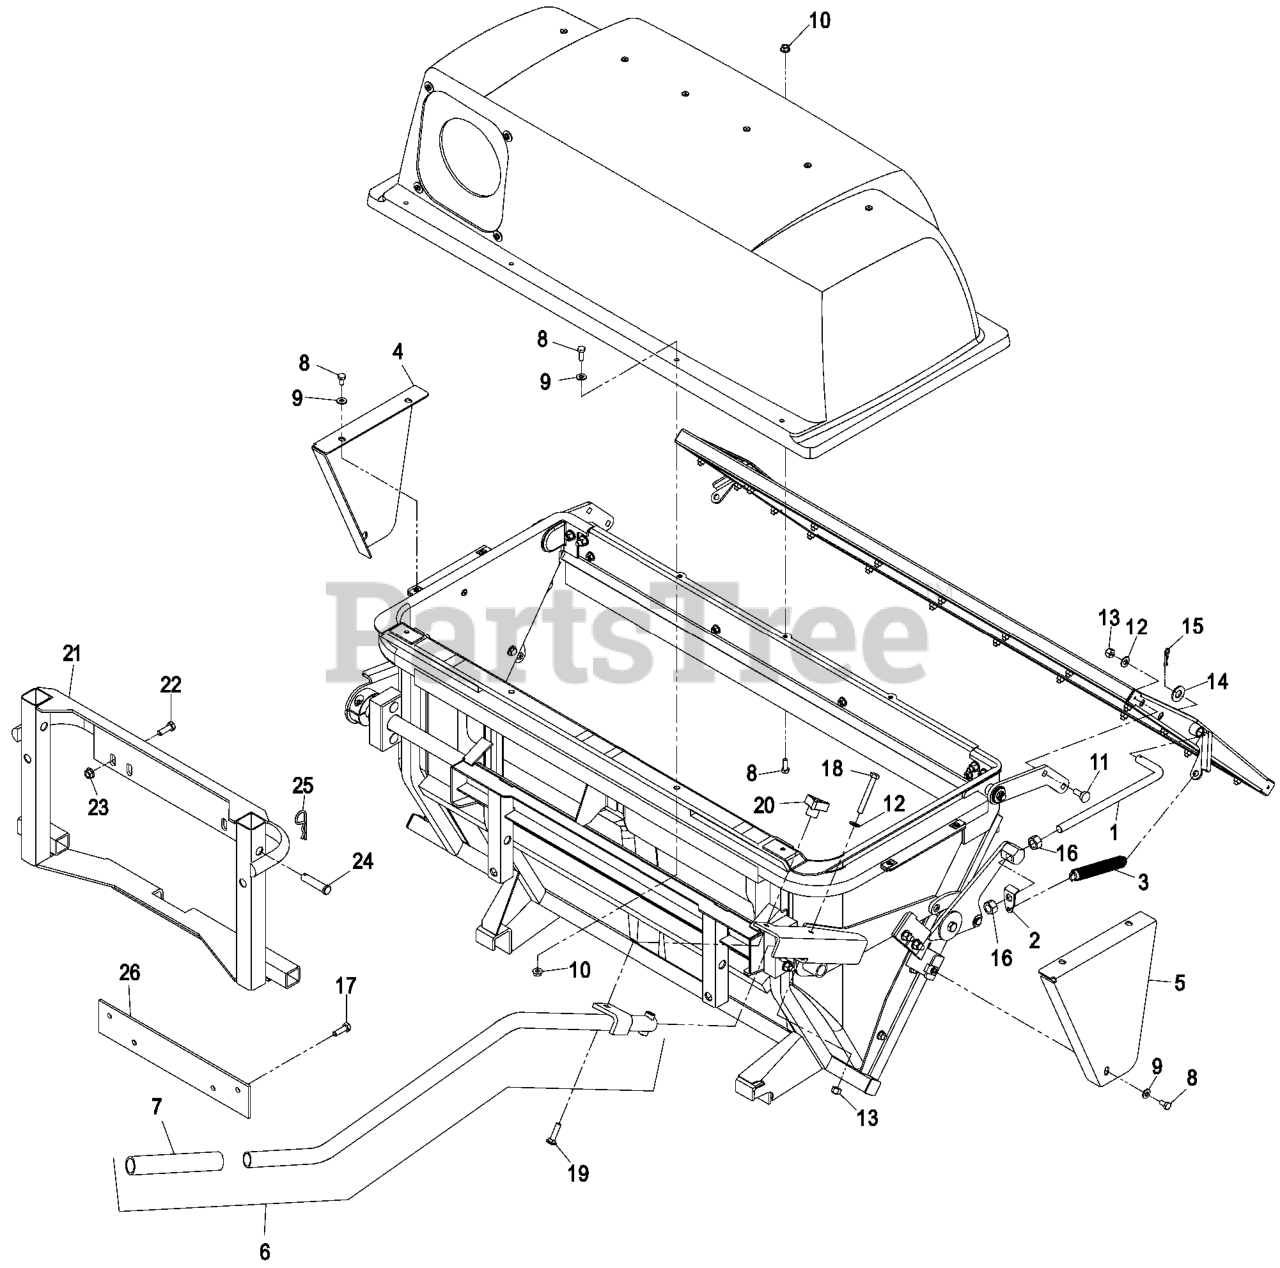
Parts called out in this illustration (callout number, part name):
1	LINK-DOOR
2	ANCHOR-SPRING
6	HANDLE ASM
7	HANDLE-GRIP
8	SCREW-HH
9	WASHER-FLAT
11	SCREW-CARR
12	WASHER-PLAIN
13	NUT-LOCK, NI
14	WASHER-FLAT
15	PIN-COTTER
16	NUT-HEX
17	SCREW-HH
18	SCREW-HH
19	Bolt-Carriage 5/16-18 X 1 1/4
20	KNOB-3 PRONG
21	MOUNT-BAGGER
22	SCREW-HH
24	PIN-CLEVIS
25	PIN-COTTER
26	SPACER,COUNTERWEIGH
